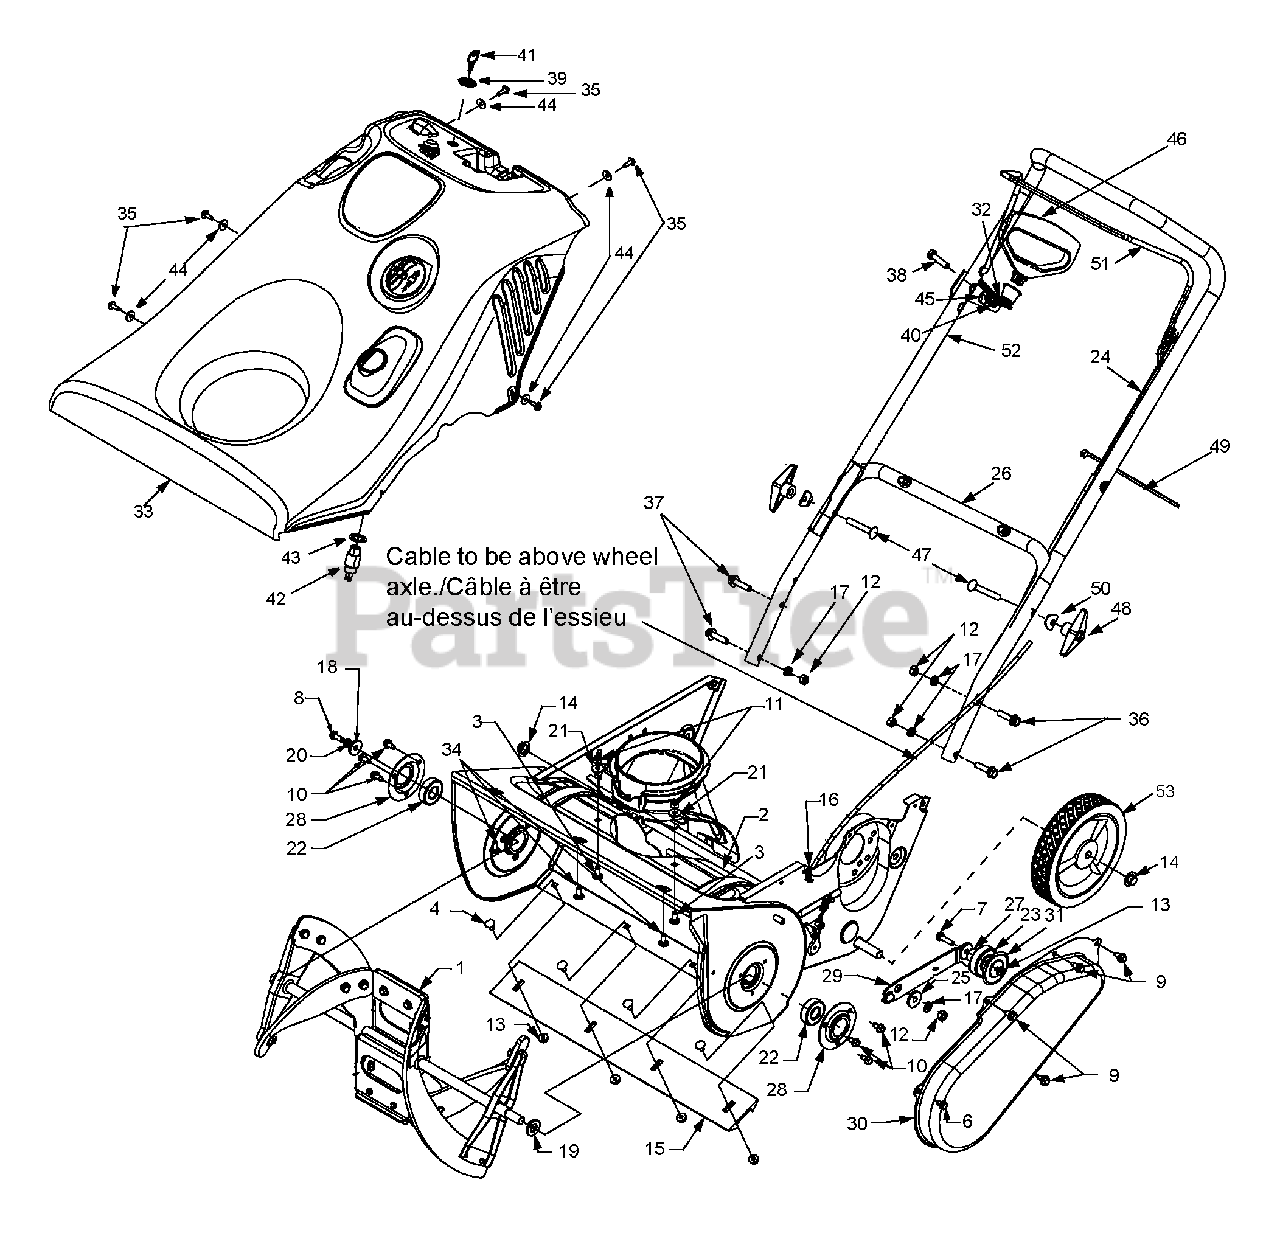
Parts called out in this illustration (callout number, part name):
1	Auger Ass'y 21" comp. w/Solid Shaft
4	Carriage Bolt 1/4-20 x .50" LG
5	Truss Mach Scr 5/16-18 x .75
6	Hex "B" Tap Scr. 1/4 DIA x .38" Lg
7	Hex Screw 1/4-20 x 1.00
8	Thd Forming Scr. 1/4-20 x .75
9	Hex B-Tap Scr 1/4-28 x .25" Lg
10	Hex Tap Scr. 1/4-20 x .50" LG.
11	Hex Ins. Locknut 1/4-20
12	Hex Nut 5/16-18 hd. (Gr. 5)
13	Hex L-Flanged Nut
14	Push Cap x 1/2" Rod
15	Shave Plate
16	Extension Spring .33 OD x 1.12 Lg.
17	L-Wash 5/16 ID
18	Flat Washer .25 ID x .93 OD x .125
19	Flat Washer .50 ID x 1.00 OD x .125
20	L-Wash 1/4 ID
21	Flat Washer .260 x .687 x .062
22	Ball Bearing 17 x 40 x 12
23	Ball Bearing .787 ID x 1.85 OD x .56
24	Clutch Cable
25	Shoulder Spacer .25 THK
27	Flg. Spacer .777 OD x .260 ID x .550
31	Bearing Washer 2.12 OD x .255 ID
32	Mitten Grip Bracket Ass'y
33	Shroud 7HP Yellow, Elec. Start, w/o Crk
33	Shroud 5HP Yellow, Elec. Start, w/o Crk
34	Hex Tapp Scr 1/4 x .75" Lg.
35	Hex Wash B-Tapp Scr #10 x .62" Lg.
36	Hex Scr. .312-18 x 1.250
37	Hex Scr. 5/16-18 x 1.50 Gr. 5
38	Hex Scr. 5/16-18 x 1.375 Gr. 5
39	Hex Nut 5/8-32 x .12 Special
40	Hex Ins. L-Nut 5/16-18
41	Ignition Key
42	Key Switch-Electric Start
43	L-Washer Internal
44	Flat Washer .218" ID x .62" OD
45	Saddle Wash. .320 ID x .937 OD
46	Recoil Handle, Mitten
47	Carriage Bolt 5/16-18 x 2.0
48	Handle Knob Assembly
49	Hex Screw 5/16-24 x .75
50	Carriage Bolt 5/16-18 x .75
53	Wheel-Star, 7.5 x 1.5 Yellow
